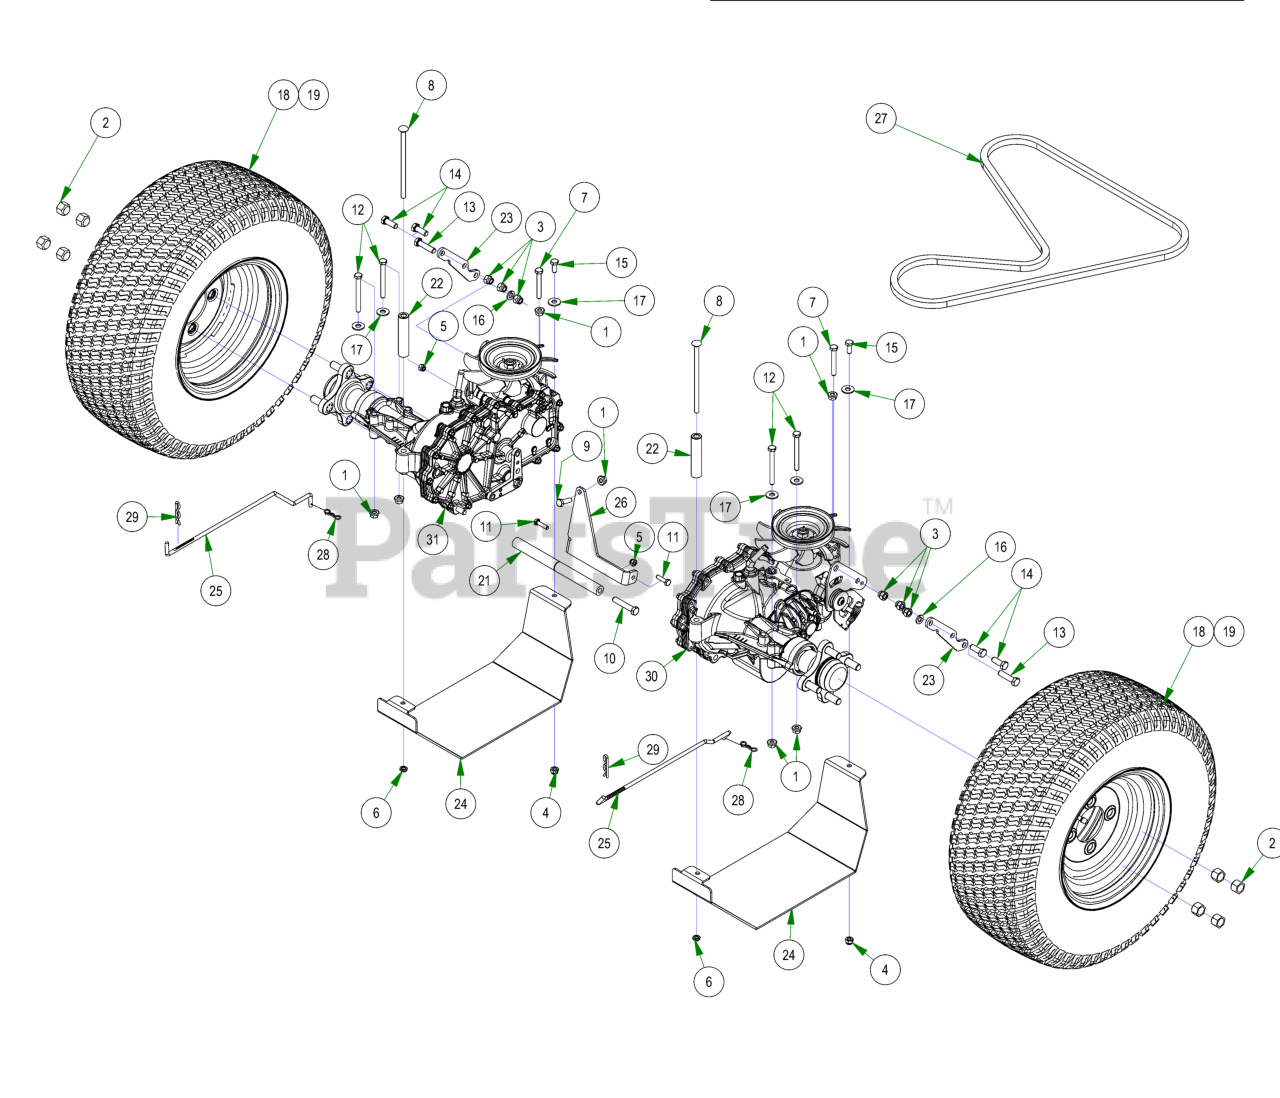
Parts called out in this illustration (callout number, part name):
1	5/16-18 NYLON INSERT FLANGE LOCKNUT ZINC
2	Acorn Lug Nut
3	3/8-16 NYLON INSERT LOCKNUT ZINC
4	5/16-18 NYL INS L/N ZC
5	1/4-20 NYLON INSERT LOCKNUT ZINC
6	5/16-18 NYLON INSERT JAM LOCKNUT ZINC
7	5/16-18 X 2-1/4 HEX CAP SCREW (GR.5) ZINC
8	5/16-18 X 6 CARRIAGE BOLT (GR.5) ZINC
9	5/16-18 X 1 HEX CAP SCREW (GR.5) ZINC
10	3/8-16 X 2 HEX CAP SCREW (GR.5) ZINC
11	1/4-20 X 1 HEX CAP SCREW (GR.5) ZINC
12	5/16-18 X 3 HEX CAP SCREW (GR.5) ZINC
13	3/8-16 X 1-1/2 HEX CAP SCREW (GR.5) ZINC
14	3/8-16 X 1 GR 5 Hex Bolts Zinc
15	5/16-18 X 3/4 HEX CAP SCREW (GR.5) ZINC
16	3/8 SPLIT LOCKWASHER ZINC
17	5/16 USS FLAT WASHER (7/8 OD) ZINC
18	21 x 8.5 - 10 turf assembly Black Wheel
19	21x7-10 Assy-36" Walk Behind Black Wheel
21	2017 Transaxle Spacer-Walker
22	2017 Transaxle Spacer
23	2020 Walk-Behind Hydro Plate Extension
24	2020 Walk Trans Skid Plate
25	2023 Walk Neutral Rod 5.9
26	Walk Brake Pull Bracket-Painted
27	2020 Walk-Behind Pump Belt
29	Neutral Rod Clip
30	Walk Behind Transaxle Left 3100
31	Walk Behind Transaxle Right 3100
